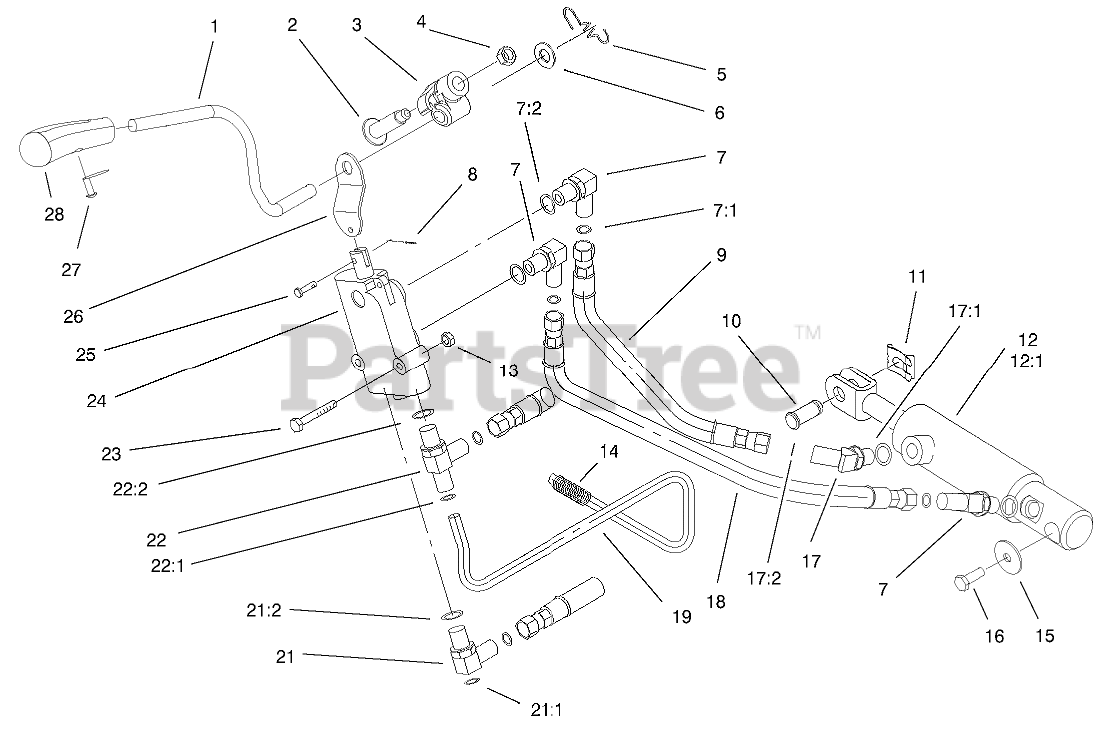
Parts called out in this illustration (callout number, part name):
1	HANDLE-LIFT
2	BOLT-SHOULDER
3	TRUNNION-LEVER, LIFT
4	NUT-JAM, LOCKING
5	SPRING-EXTENSION, LIFT
6	WASHER
7	FITTING-HYD, 90 DEGREE
7:1	O-RING
7:2	O-RING
8	PIN-COTTER
9	HOSE ASM
10	PIN-CLEVIS
11	CLIP-PIN
12	LIFT CYLINDER ASM
13	NUT-LOCK, NI
14	COVER-BRACE
15	WASHER-FLAT
16	SCREW-THREAD LOCKING
17	FITTING-HYD, 45 DEGREE
17:1	O-RING
17:2	O-RING
18	HOSE ASM
19	TUBE-HYD
21	FITTING-HYD, 90 DEGREE
21:1	O-RING
21:2	O-RING
22	FITTING-HYD, TEE
22:1	O-RING
22:2	O-RING
23	SCREW-HH
24	VALVE-HYD
25	PIN-CLEVIS
26	LINK-LIFT
27	SCREW-PPHTF
28	Knob-Lift (only on: 73547)
28	Knob-Lift (Int-l)(only on: 73580)
